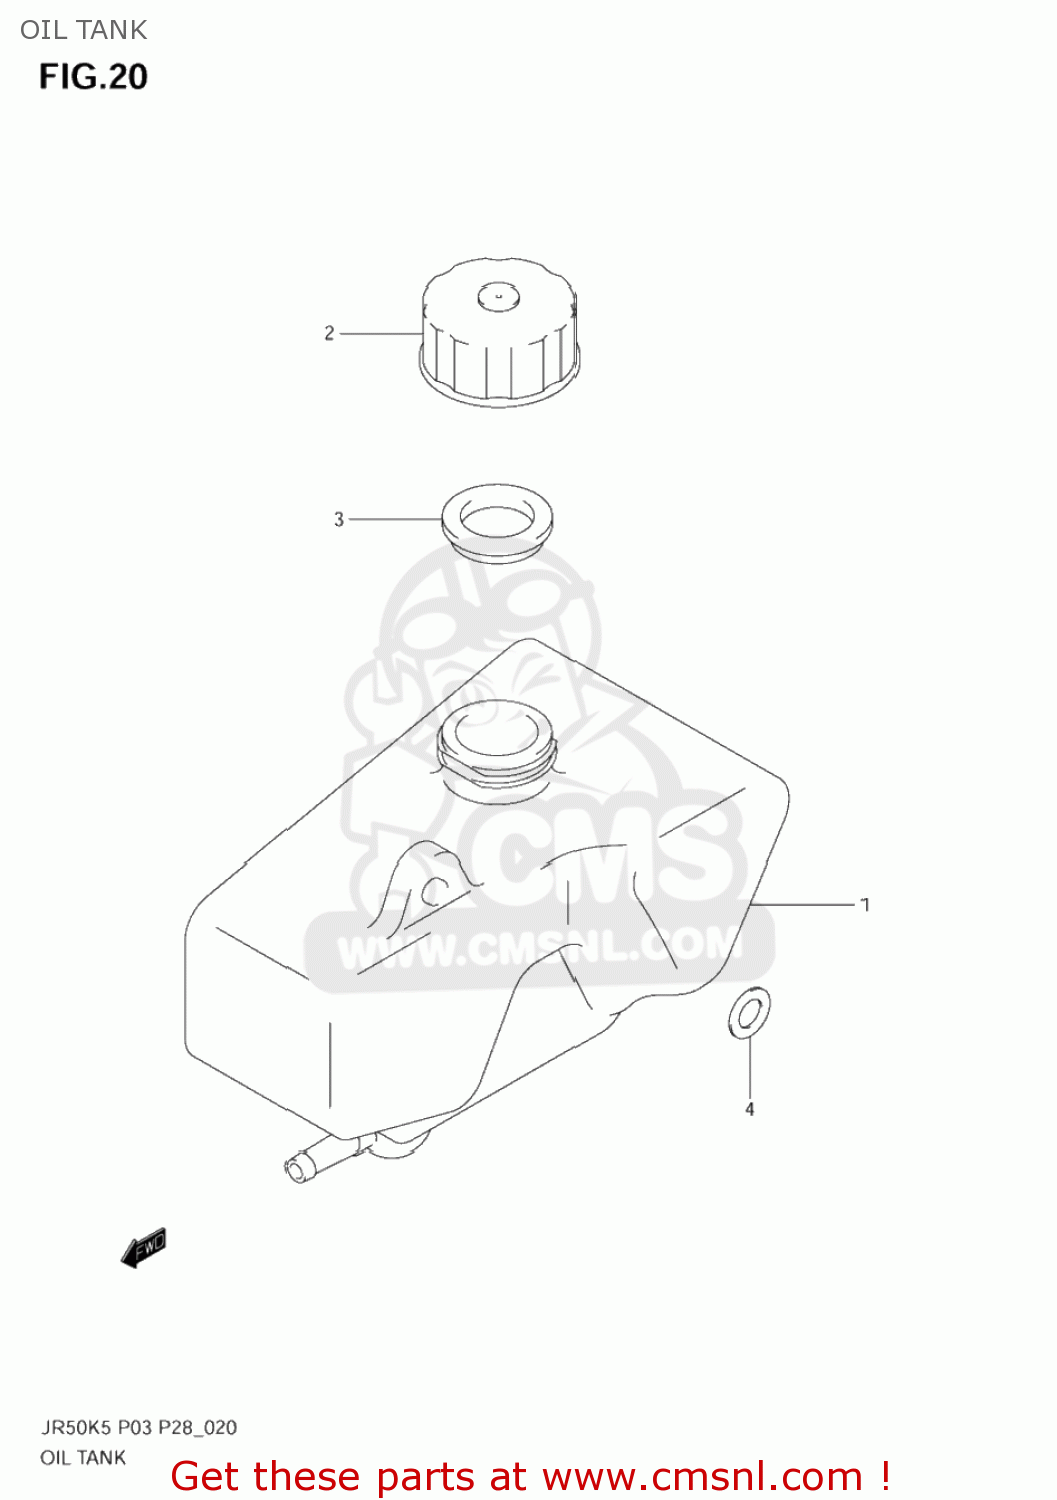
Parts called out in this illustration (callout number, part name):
1	TANK,OIL
2	CAP,OIL TANK FILLER
3	GASKET,OIL TANK CAP (NAS)
4	WASHER(10.5X18X1)
